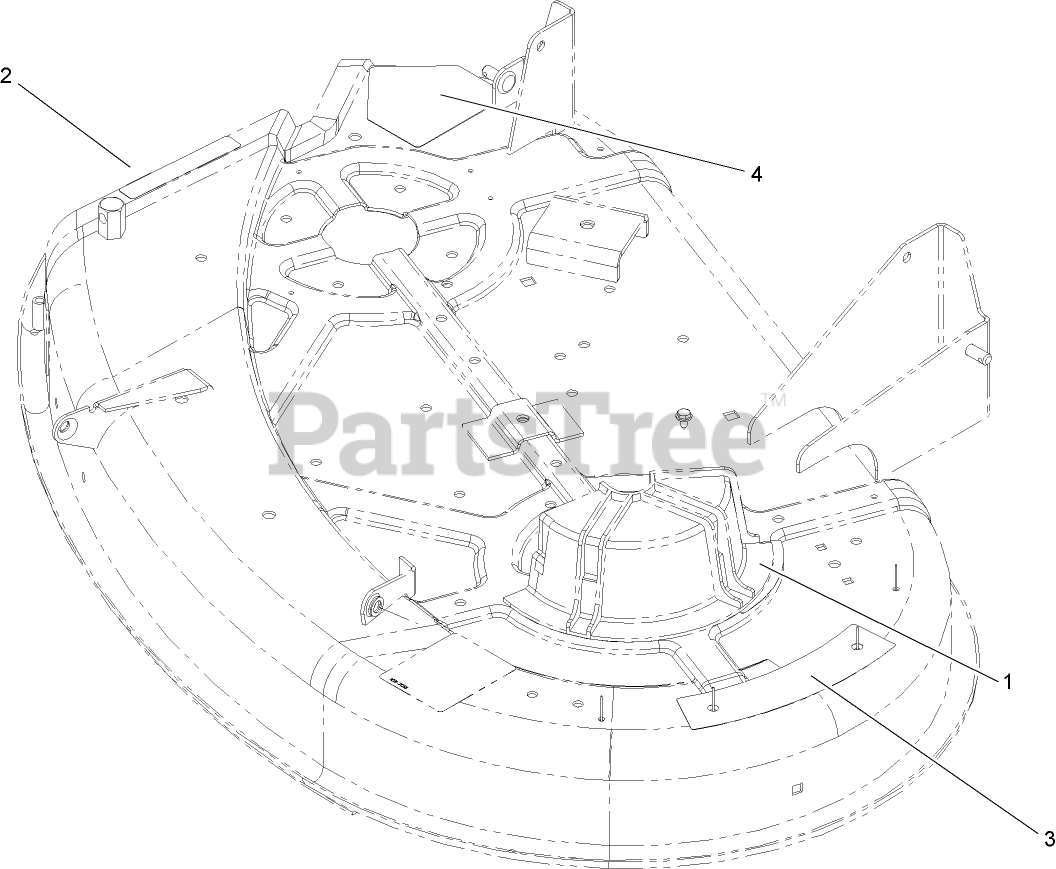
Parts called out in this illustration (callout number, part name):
1	DECAL-DANGER, SHIELD
2	DECAL-DANGER
3	DECAL-DANGER
4	DECAL-DANGER
